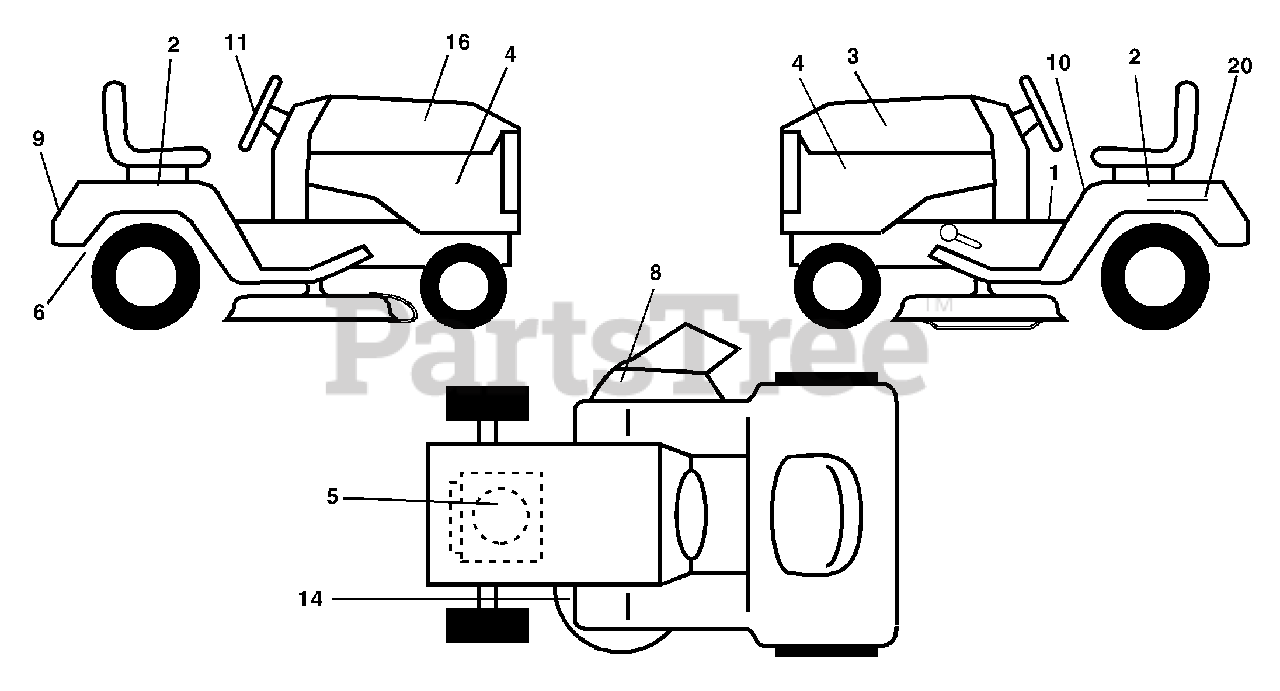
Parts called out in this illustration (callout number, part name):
1	Decal Oper
2	Decal Fender Auto
3	Decal Hood LH
4	Decal Side Panel Logo
5	Decal HP Engine
6	Decal By Pass Lt Hydro
8	Decal Mower Warn Keep Hand Away
9	Decal Fender Logo
10	Decal Fender Danger E/F
11	Decal Ins Strg Whl
14	Decal V-Belt Schematic
16	Decal Hood Rh
20	Decal Bat Dan/Psn
